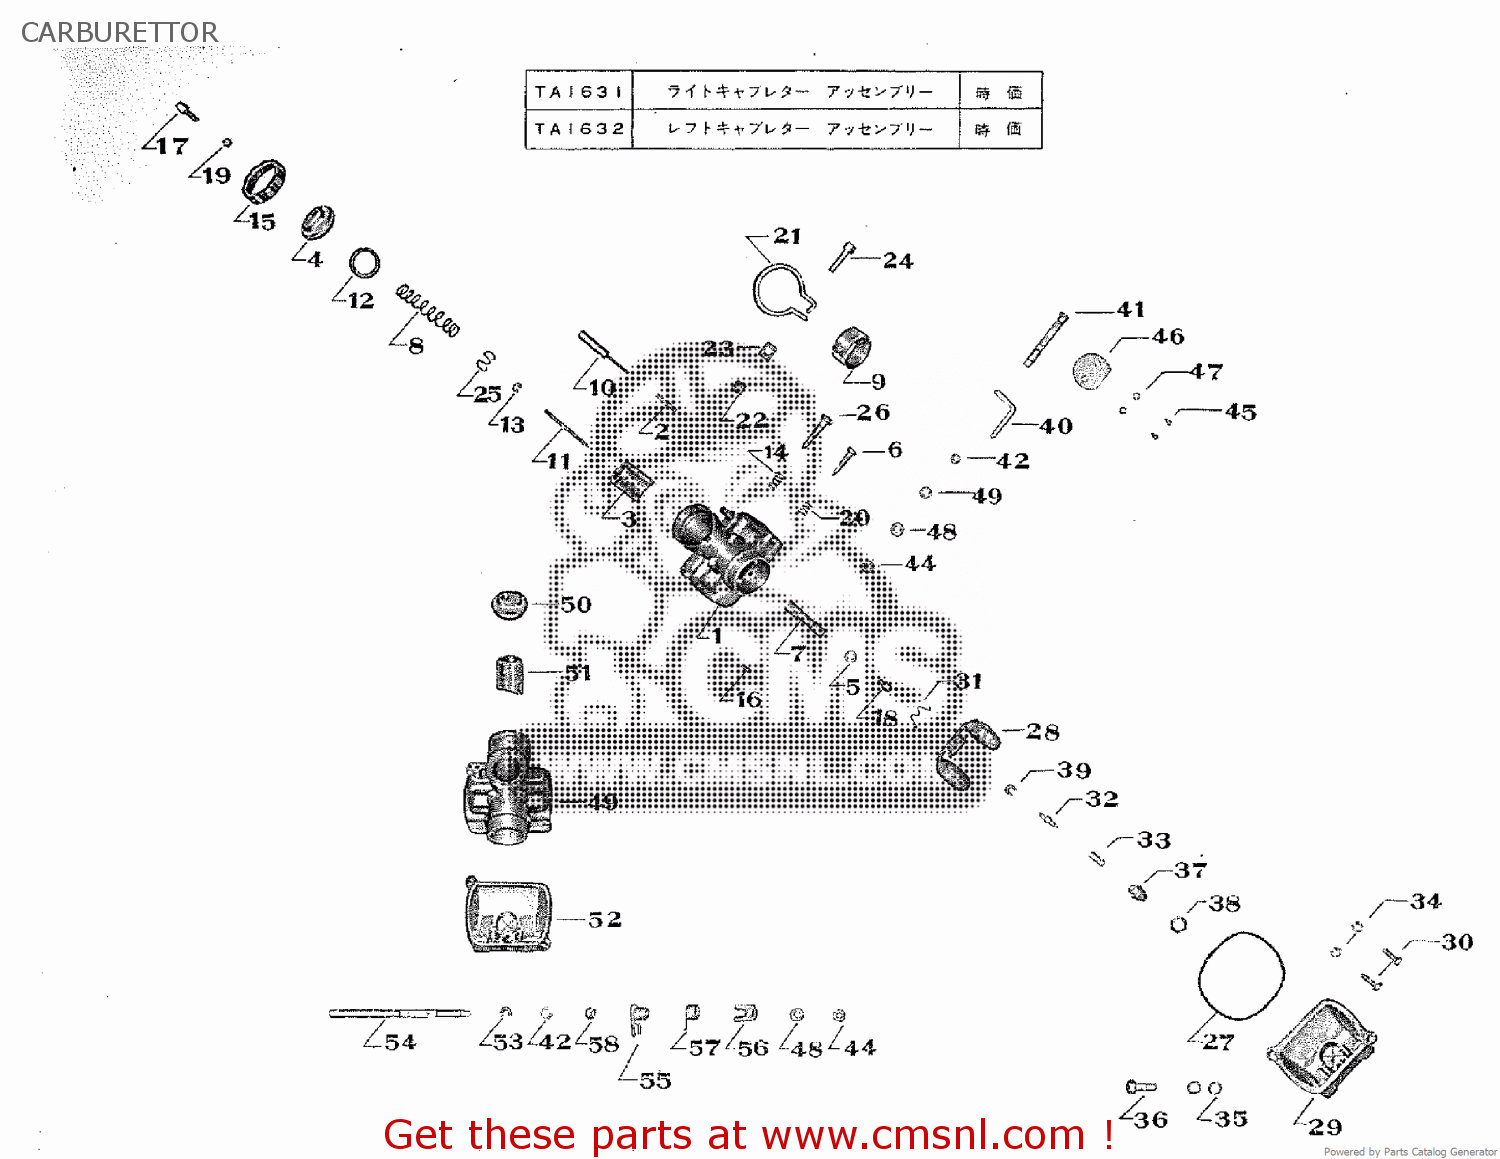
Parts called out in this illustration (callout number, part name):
1	RIGHT MIXING CHAMBER BODY
2	TICKLER SPRING
3	RIGHT THROTTLE VALVE
4	RIGHT MIXING CHAMBER TOP
5	WASHER
6	AIR ADJUSTER SCREW
7	NEEDLE JET
8	THROTTLE VALVE SPRING
9	INSULATING PACKING
10	TICKLER CAP
11	JET NEEDLE
12	MIXING CHAMBER CAP PACKING
13	JET NEEDLE CLIP
14	THROTTLE STOP SPRING
15	MIXING CHAMBER CAP
16	PILOT JET
17	CABLE ADJUSTER
18	MAIN JET
19	CABLE ADJUSTER LOCK NUT
20	AIR ADJUSTER SPRING
21	OUTLET CLIP
22	OUTLET CLIP NUT
23	OUTLET CLIP WASHER
24	OUTLET CLIP SCREW
25	SPRING SEAT
26	THROTTLE STOP SCREW
27	FLOAT CHAMBER PACKING
28	FLOAT COMP.
29	RIGHT FLOAT CHAMBER BOBY
30	FLOAT CHAMBER SET SCREW
31	FLOAT STOP
32	FLOAT VALVE
33	OUTER SPRING
34	5MM SPRING WASHER
35	BANJO WASHER
36	BANJO BOLT
37	VALVE SEAT
38	PACKING
39	VALVE STOP SPRING AIR SHUTTER
40	ARM (C)
41	CHOKE SHAFT
42	AIR SHUTTER WASHER
43	AIR SHUTTE SPRING
44	6MM NUT
45	3X5 CROSS SCREW
46	AIR SHUTTER
47	3MM SPRING WASHER
48	WASHER
49	MIXING CHAMBER BODY
50	MIXING CHAMBER TOP
51	THROTTLE VALV FLOAT CHAMBER
52	FLOAT CHAMBER BODY
54	CHOKE SHAFT
55	ARM COMP. (B)
56	ARM (A)
57	ARM SPRING
58	COLLAR
